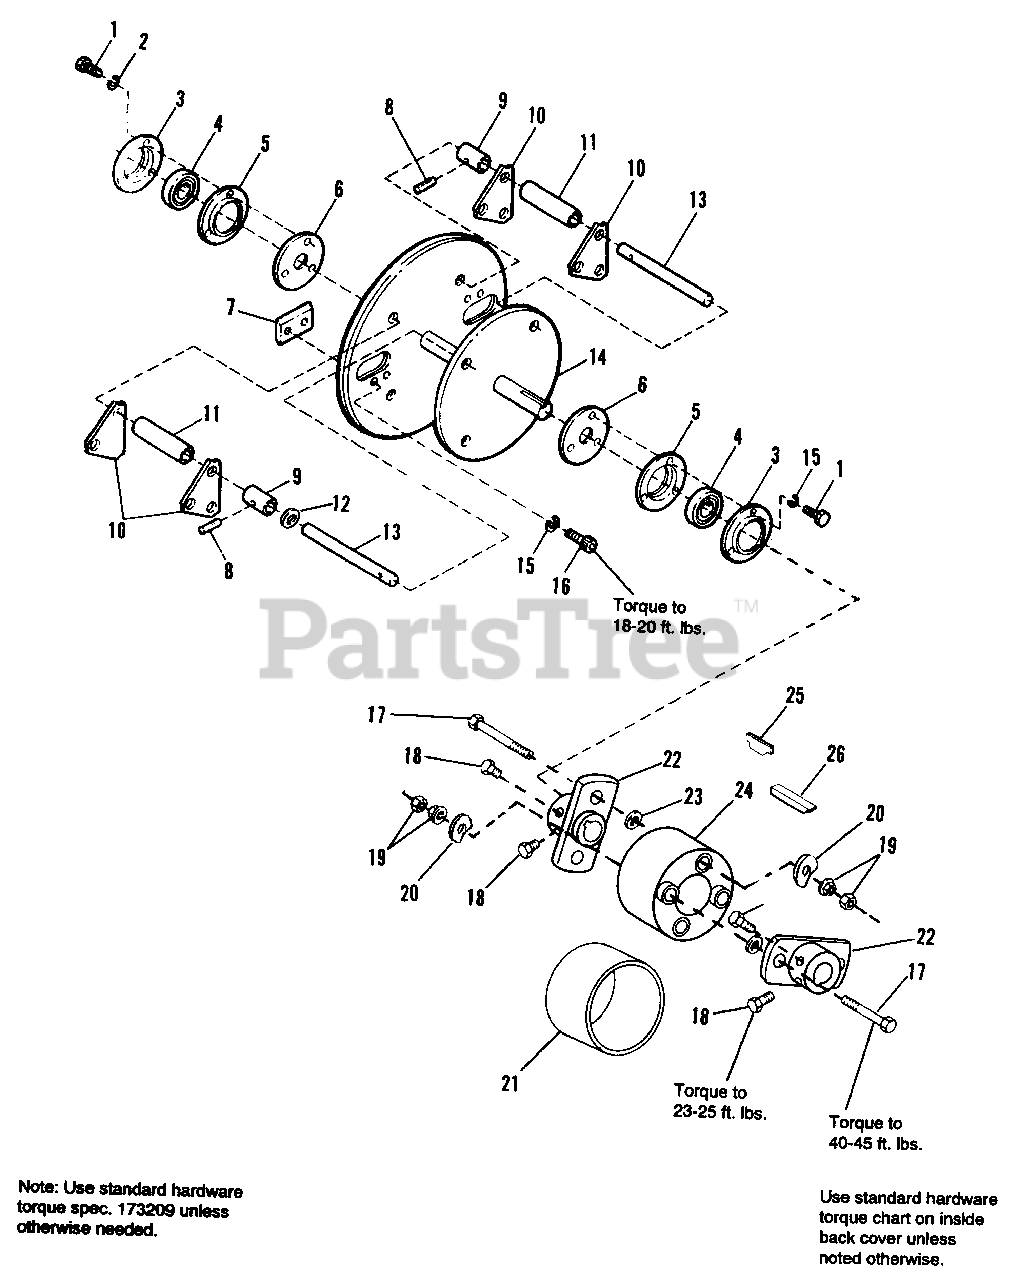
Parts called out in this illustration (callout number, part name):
1	CAPSCREW, Hex, 5/16-18 x 5/8, Gr.5
2	LOCKWASHER, 5/16
3	FLANGE, Bearing w/Zerk Fitting
4	BEARING, Cartridge
5	FLANGE, Bearing
6	GUARD, Bearing
8	ROLL PIN, 3/16 x 3/4
9	SPACER, Short, 17/32 x 3/4 x 1-1/4
10	HAMMER, Triangle
11	SPACER, Long, 17/32 x 3/4 x 2-1/2
12	WASHER, Plain, 33/64 x 7/8 x 1/16
13	SHAFT, Hammer, 1/2 x 4-7/8
14	ROTOR ASSY.
15	LOCKWASHER, 5/16
16	CAPSCREW, 5/16-18 x 5/8
17	CAPSCREW, Hex, 3/8-16 x 2-3/4, Gr.8
18	CAPSCREW, Hex, Socket Hd., 5/16-18 x 3/4, Gr.8
19	NUT, Hex, Lock, 3/8-16
20	WASHER, Special, 13/32 x 1-1/2 x 1/8
21	SLEEVE, Coupler
22	HUB & PLATE ASSY.
23	WASHER, Plain, 13/32 x 1 x 1/8
24	COUPLER, Drive
25	KEY, Hi-Pro
26	KEY, Square, 1/4 x 1/4 x 2-1/4
